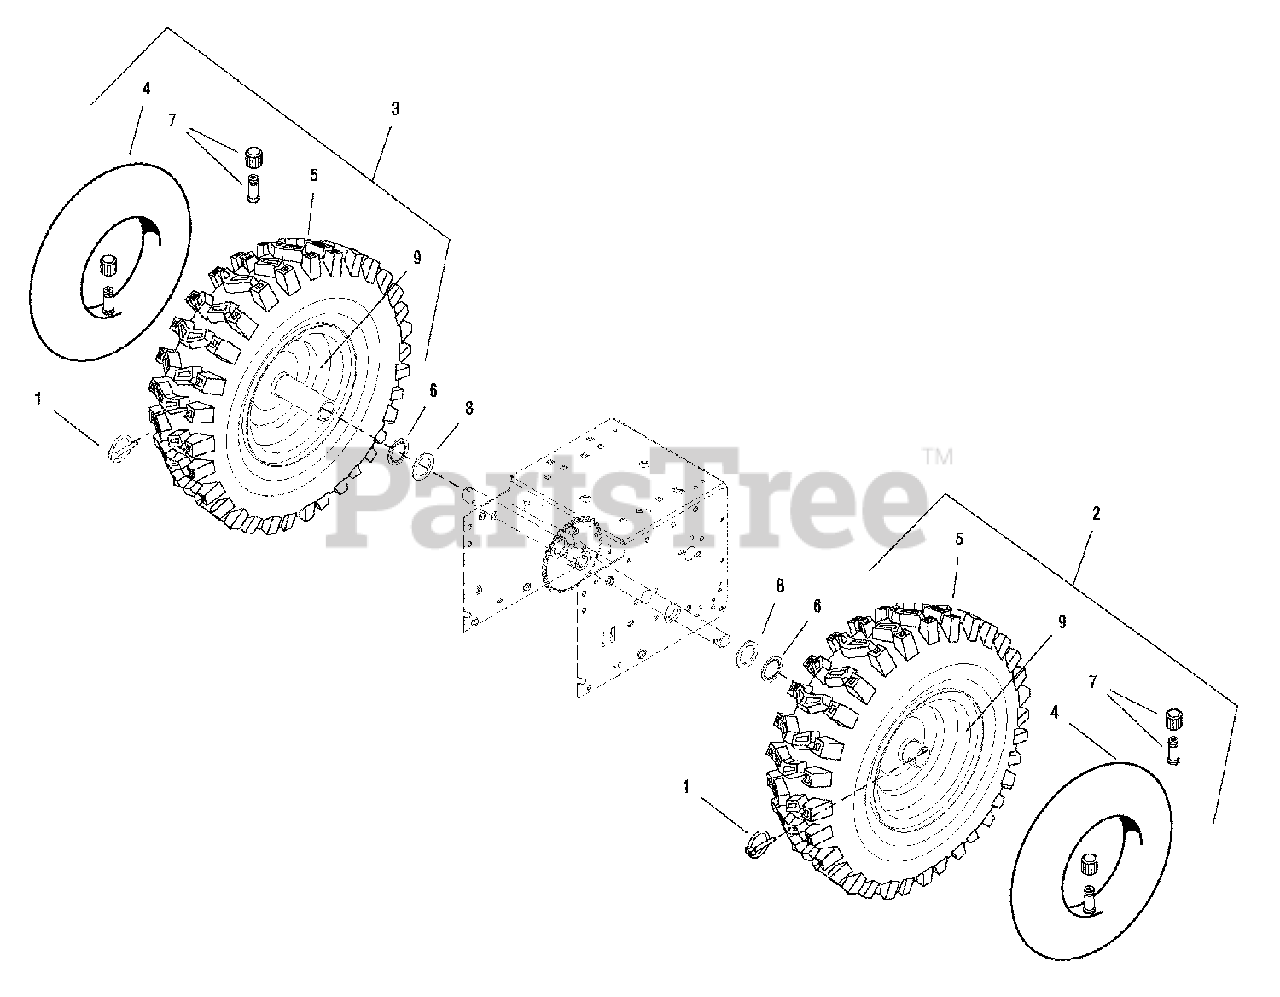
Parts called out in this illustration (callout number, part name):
1	PIN, Klik .313 x 1.97
1	PIN, Klik 1/4 x 1-3/4
2	WHEEL & TIRE ASSEMBLY, 15 x 5 L.H & R.H.
2	WHEEL & TIRE ASSEMBLY, 15 x 5 L.H.
2	WHEEL & TIRE ASSEMBLY, 16 x 4.8 L.H.
3	WHEEL & TIRE ASSEMBLY, 15 x 5 L.H & R.H.
3	WHEEL & TIRE ASSEMBLY, 15 x 5 R.H.
3	WHEEL & TIRE ASSEMBLY, 16 x 4.8 R.H.
4	TUBE, Tire 4.10/3.50-6 L.H.
4	TUBE, Tire 4.80/4.00 L.H. & R.H.
5	TIRE, 15 x 5.00-6, 2 PLY, KENDA L.H.
5	TIRE, 4.80/4.00-8 L.H. & R.H.
6	RETAINING RING, Extension, #75 3/4 Self Lock
7	VALVE STEM & CAP
8	WASHER, Flat
9	HUB, Wheel L.H.
9	HUB, Wheel 3.756 Wide 8. L.H.
9	HUB, Wheel 3.75 Wide 8. R.H.
